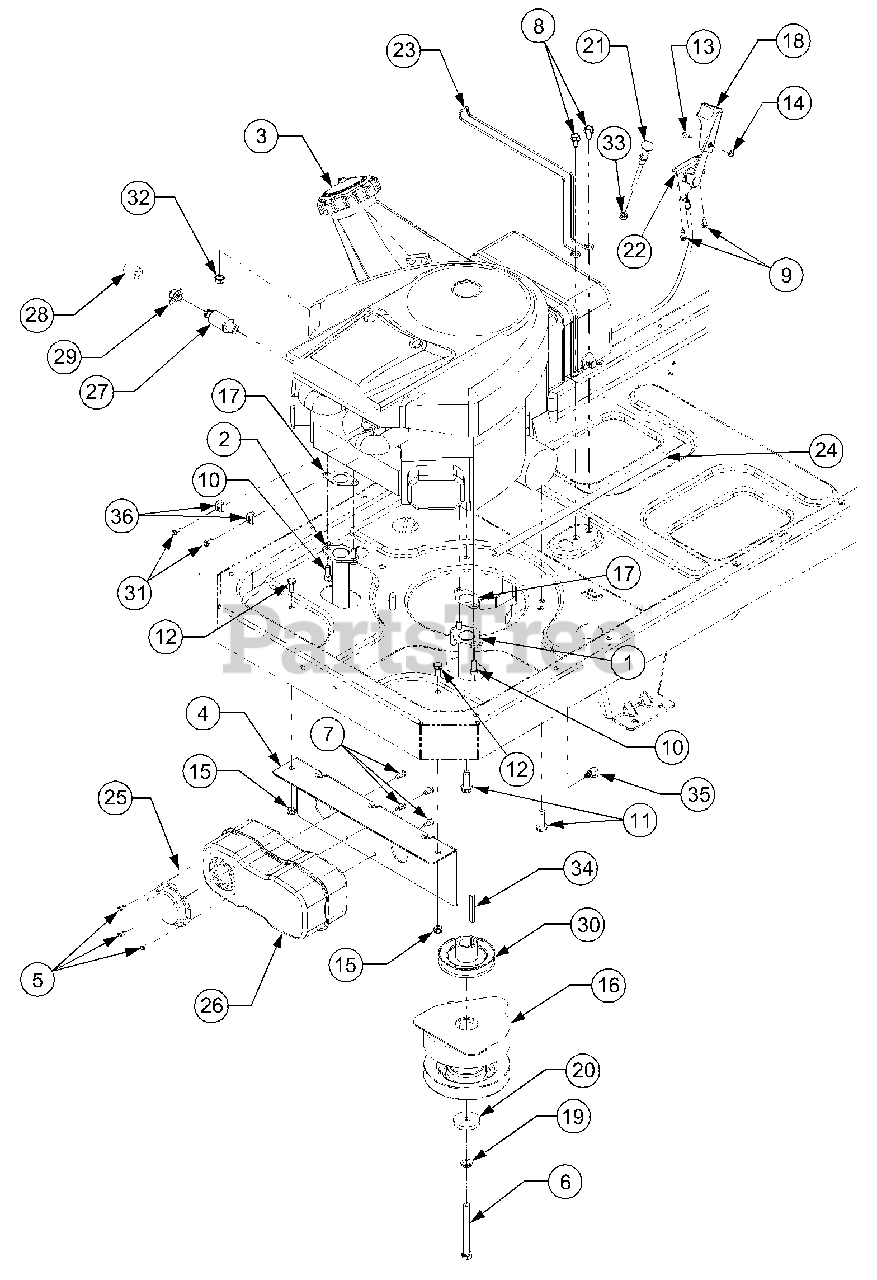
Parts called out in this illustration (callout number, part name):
1	Tube, Exhaust RH
2	Tube, Exhaust LH
3	Tank, Fuel, 3.0 Gal.
4	Bracket, Muffler Mounting
5	Screw, Hex Wash. Hd. Tapp #8-18 x .5
6	Screw, Hex Cap, 7/16-20 x 4.0 GR5
7	Screw, Hex Wash. Hd. Tapp 1/4-20 x .5
8	Screw, Hex Wash. Hd. Tapp 5/16-12 x .75
9	Screw, Hex Wash. Hd. Tapp #12-16 x .5
10	Screw, Socket Hd. 5/16-18 x .75
11	Screw, Hex Wash. Hd. Tapp 3/8-16 x 1.25
12	Screw, Hex Cap, 5/16-18 x .75 GR5
13	Screw, Truss Hd. Mach. #8-32 x .375
14	Nut, Hex, #8-32
15	Nut, Hex Insert Lock, 5/16-18 GR5
16	Clutch Assembly, Electric PTO
17	Gasket, Exhaust
18	Knob, Throttle Control
19	Washer, Lock, 7/16
20	Washer, Flat, .438 x 1.75 x .25
21	Cable, Choke, 61Lg
22	Cable, Throttle, 39.0 Lg
23	Wire, Tank Mounting
24	Hose, Fuel Line 16 inches
25	Deflector, Muffler
26	Muffler
27	Valve, Oil Drain
28	Hose, Oil Drain Extension
29	Cap, Oil Drain Valve
30	Pulley, Drive, 3.25 Dia.
31	Screw, Hex Wash. Hd. Tapp #10-32 x 0.625
32	Nut, Hex Sems, 1/4-20
33	Nut, Hex Jam, 3/8-24 GR2
34	Key, Square, 1/4 x 2.25
35	Clip, Cable Retainer
36	Clamp, Casing
